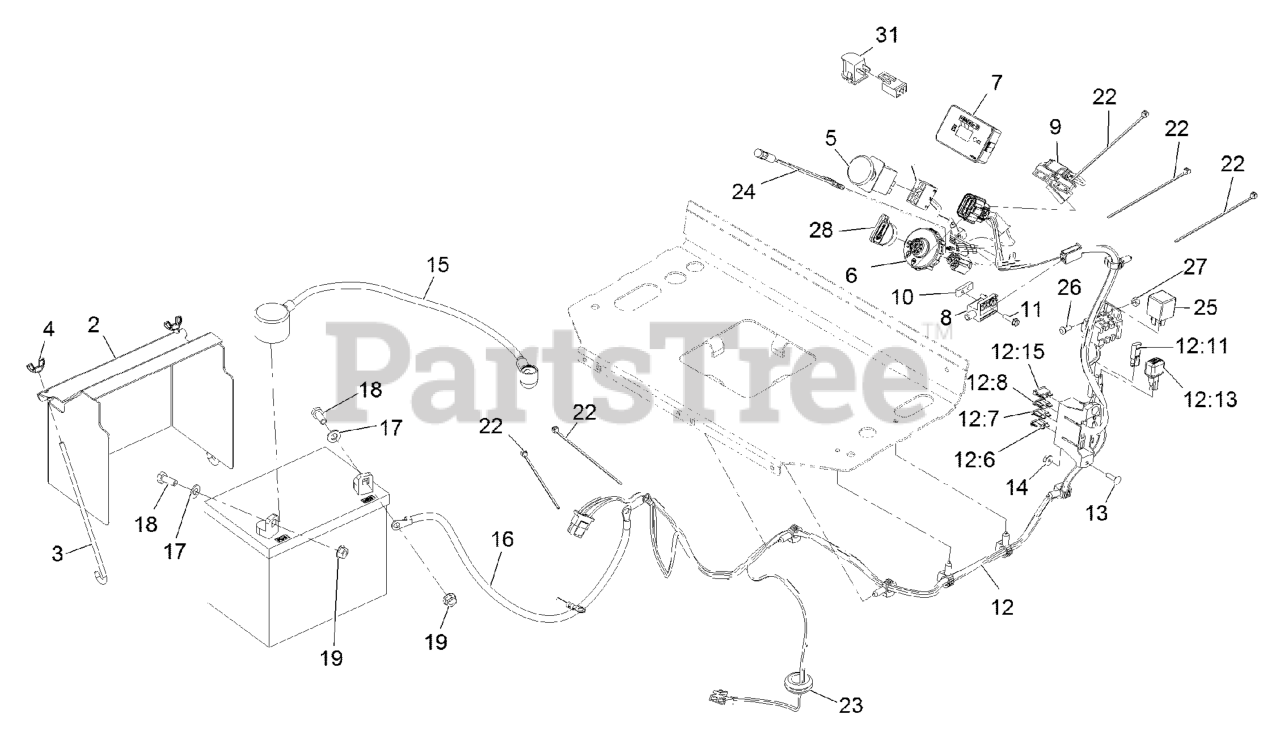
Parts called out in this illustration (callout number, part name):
2	COVER-BATTERY
3	BOLT-HOLDDOWN
4	WINGNUT
5	SWITCH-PTO, ON-ON
7	MODULE-HOUR METER
8	SWITCH-CLOSED, NORMALLY
9	HARNESS-SWITCH, REED
10	PLATE-TAPPED
11	SCREW-HWH
12	HARNESS, WIRE
12:6	FUSE-BLADE, 30 AMP
12:7	FUSE-BLADE, 25 AMP
12:8	FUSE-BLADE, 10 AMP
12:15	FUSE-BLADE, 15 AMP
13	SCREW-CARR
15	CABLE-BATTERY, POSITIVE
16	CABLE-BATTERY, BLACK
17	WASHER-PLAIN
18	SCREW-HH
19	NUT-HHF, SMOOTH
22	TIE-CABLE
23	GROMMET
24	INDICATOR-LED, RED
26	SCREW-PPH
27	NUT-LOCK, NI
28	KEY-IGNITION
31	SWITCH-BAIL
